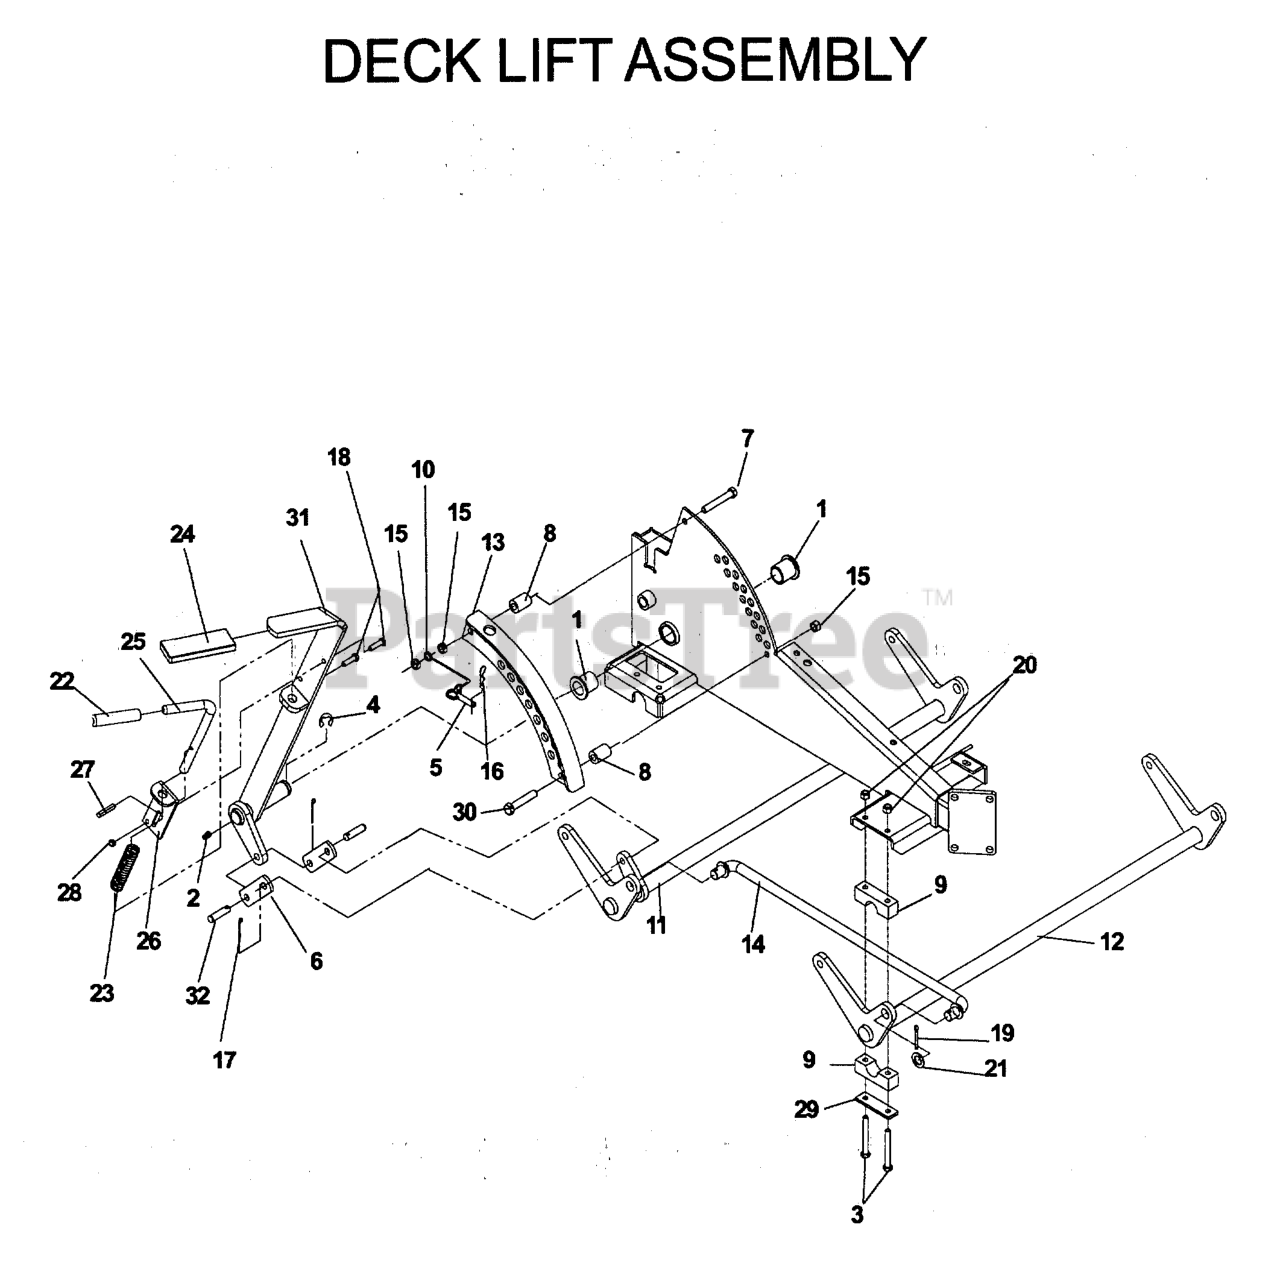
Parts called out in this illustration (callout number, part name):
1	BUSHING, FLANGED
3	HCS 5/16C X 2-3/4
4	E-RING 7/8
7	SCREW 3/8C X 2 3/4 HEX CAP
8	DECK LIFT SPACER
9	PILLOW BLOCK
11	REAR LIFT SHAFT
12	FRONT LIFT SHAFT
13	ADJUSTMENT PLATE WLDMT
14	CROSS LINK
15	NUT 3/8-16 NYLOC
16	HAIRPIN #4
17	RP_COTTER PIN 1/8 X 3/4
18	HCS 1/4C X 3/4 HCS
19	COTTER PIN
20	NUT 5/16 NYLOC
26	PIN MT, UPPER
28	NUT 1/4C CENTER LOCK
29	REINFORCEMENT BAR
30	HCS 3/8C X 2 1/2
31	LIFT LEVER WELDMENT
32	CLEVIS PIN 3/8 X 1 1/8
